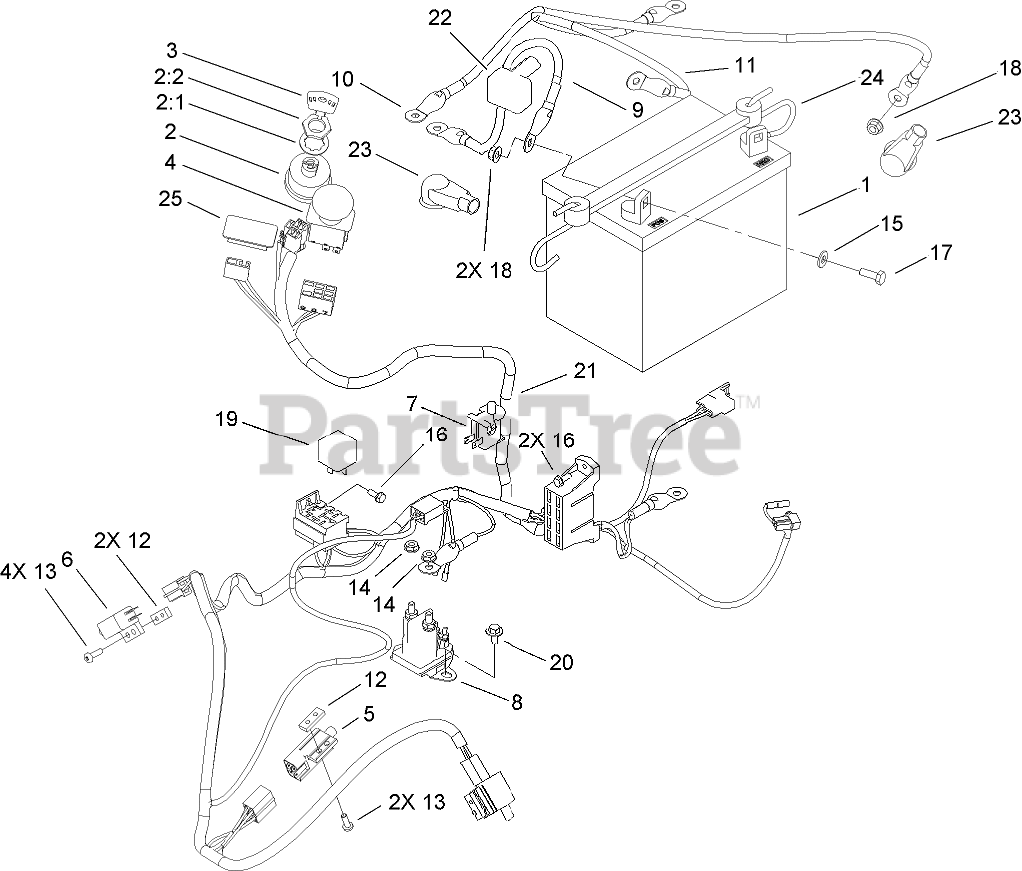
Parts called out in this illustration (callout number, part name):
1	BATTERY
2	SWITCH ASM
2:1	WASHER-TOOTH, INTERNAL
2:2	NUT-HH
3	KEY-IGNITION
4	SWITCH-PTO
5	SWITCH-INTERLOCK
6	SWITCH-OPEN, NORMALLY
7	SWITCH-BAIL
8	SOLENOID-STARTER
9	WIRE ASM
10	WIRE ASM
11	CABLE
12	PLATE-TAPPED
13	SCREW-PPHTF
14	NUT-KEPS
15	WASHER-FLAT
16	SCREW-TAPTITE
17	SCREW-HH
18	NUT-HF
19	RELAY
20	SCREW-HHFTF
21	HARNESS-WIRE
22	BOOT-TERMINAL
23	BOOT-INSULATOR, TERMINAL
24	HOLDDOWN-BATTERY
25	PLUG-HOLE
